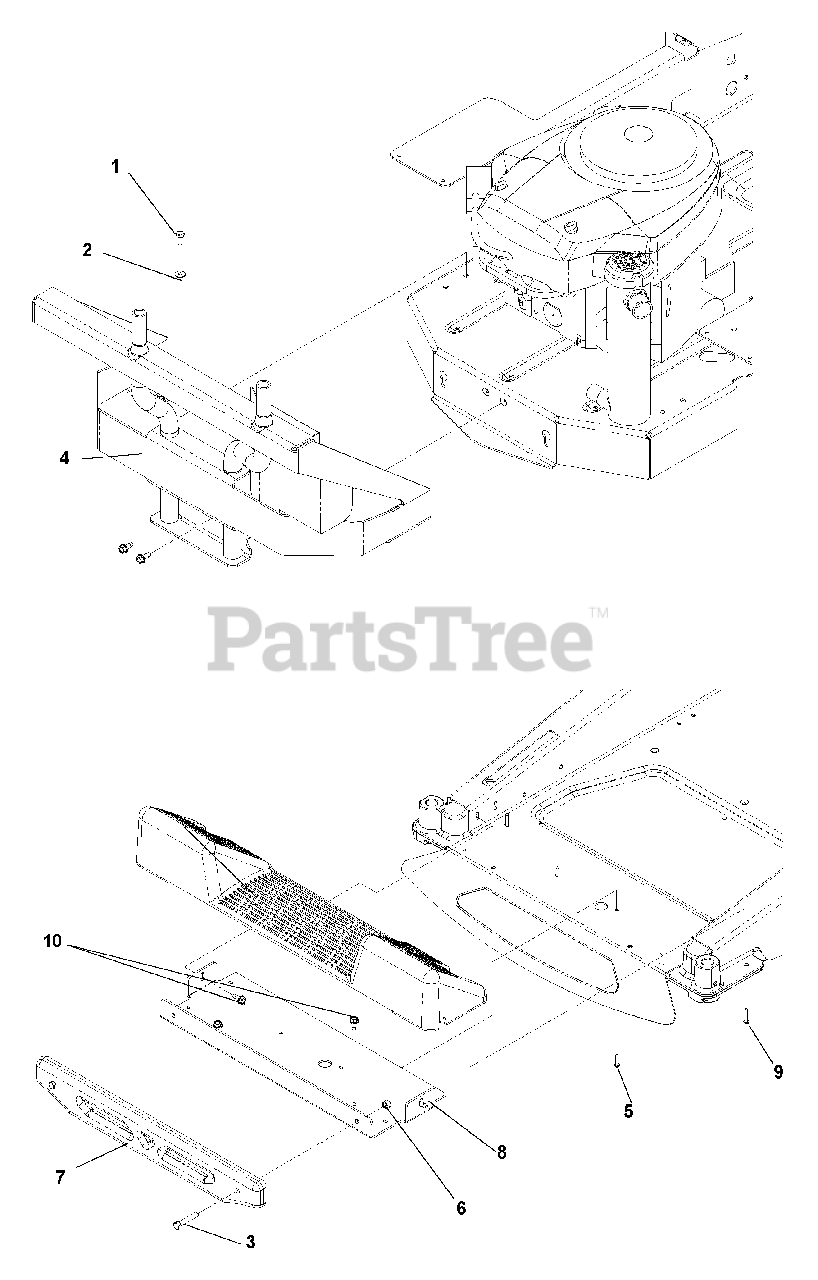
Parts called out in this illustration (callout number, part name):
1	Washer, 1/4
2	HCS, 5/16-18 x 3/4, Gr8
3	HCS, 3/8-16 x 2, Gr5
4	Hitch
5	Screw, #10-12 x 1
6	Nut, 3/8-16, nyloc
7	Cast weight
8	Weight bracket
9	Screw, #10-12 x 1 1/4
10	Bolt, 5/16-18 x x 1
